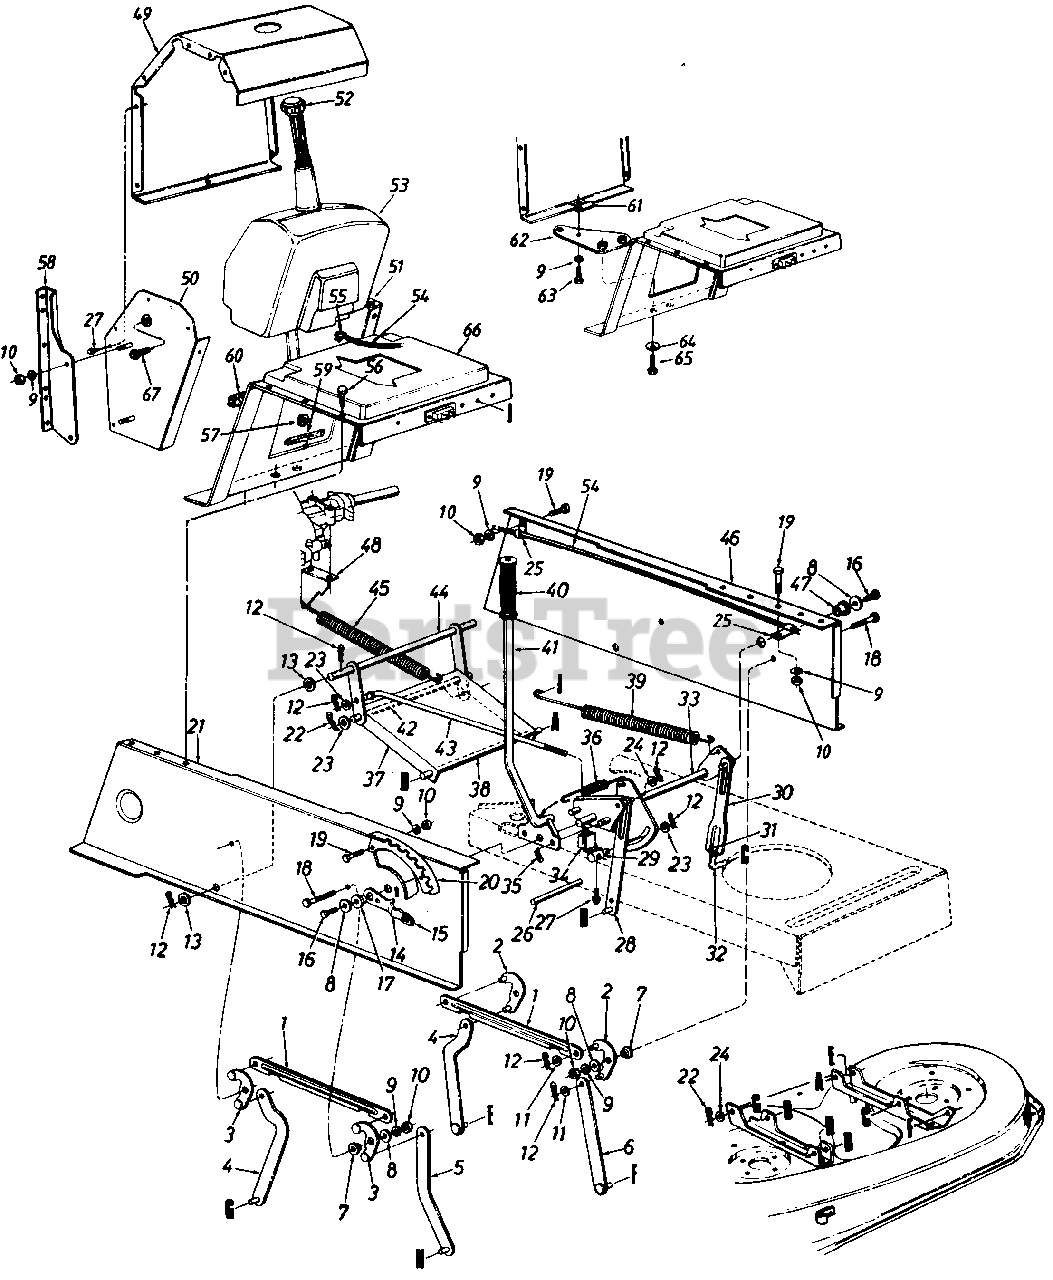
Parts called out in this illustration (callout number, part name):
1	Connecting Rod
2	Pivot Link Ass'y.-L.H.
3	Pivot Link Ass'y.-R.H.
6	Deck Hanger Link Ass'y.
7	Shld. Spacer .3/8" I.D.
8	Fl-Wash. .344" I.D. x 1.125"
9	L-Wash. 5/16" I.D.*
10	Hex Nut 5/16-18 Thd.
11	Fl-Wash. .531" I.D. x .94" O.D.
12	Cotter Pin 1/8" Dia.
13	Fl-Wash. .635" I.D. x 1.0" O.D.
14	Deck Lift-Down Stop
15	Knob
16	Hex Wash. TT-Tap Scr. 5/16-18 x .75" Lg.
17	Flange Brg. .63" I.D.
18	Hex Wash. TT-Tap Scr. 5/16-18 x .875" Lg.
19	Hex Bolt 5/16-18 x .75" Lg.
20	Index Brkt.
21	Upper Frame-R.H.
22	Inter. Cotter Pin 1/2" Dia.
23	Fl-Wash. .385" I.D. x .87" O.D.
24	Fl-Wash. .531" I.D. x .93" O.D.
25	Clamp
26	Running Board Rod
27	Truss Mach. Scr. #10 x .5" Lg.
31	Hex Jam Nut 1/2-20 Thd. (Grade 5)
32	Lift Link Adjuster
33	Lift Shaft Ass'y.
34	Safety Switch
35	Inter. Cotter Pin 3/8" Dia.
36	Extension Spring
37	Stabilizer Bracket
38	Shaft 1/2" Dia. x 10.28" Lg.
39	Extension Spring
40	Grip
41	Deck Lift Handle Ass'y.
42	Shaft 3/8" Dia. x 9.34" Lg.
43	Disengagement Rod
44	Stabilizer Shaft Ass'y.
45	Extension Spring 13.25" Lg.
46	Upper Frame-L.H.
47	Flange Brg. .632" I.D.
48	Spring Retainer Brkt.
49	Gas Tank Housing
50	Side Panel Ass'y.-R.H.
53	Gas Tank
54	Fuel Line
55	Hose Clamp
56	Hex Wash. AB-Tap 5/16 x .75" Lg.
57	Rubber Grommet
58	Mtg. Brkt.-R.H.
59	Trim Strip
60	Foam Strip
61	Speed Nut
62	Hitch Bar Ass'y.
63	Hex Bolt 5/16-18 x 1.0" Lg. (Grade 5)
64	Bell-Wash. .38" I.D. x .88"
65	Hex Wash. Tap Scr. 3/8-16 x .75" Lg.
66	Hitch Plate
67	Hex Wash. Hd. Tap Scr. 1/4-20 x.38" Lg.
